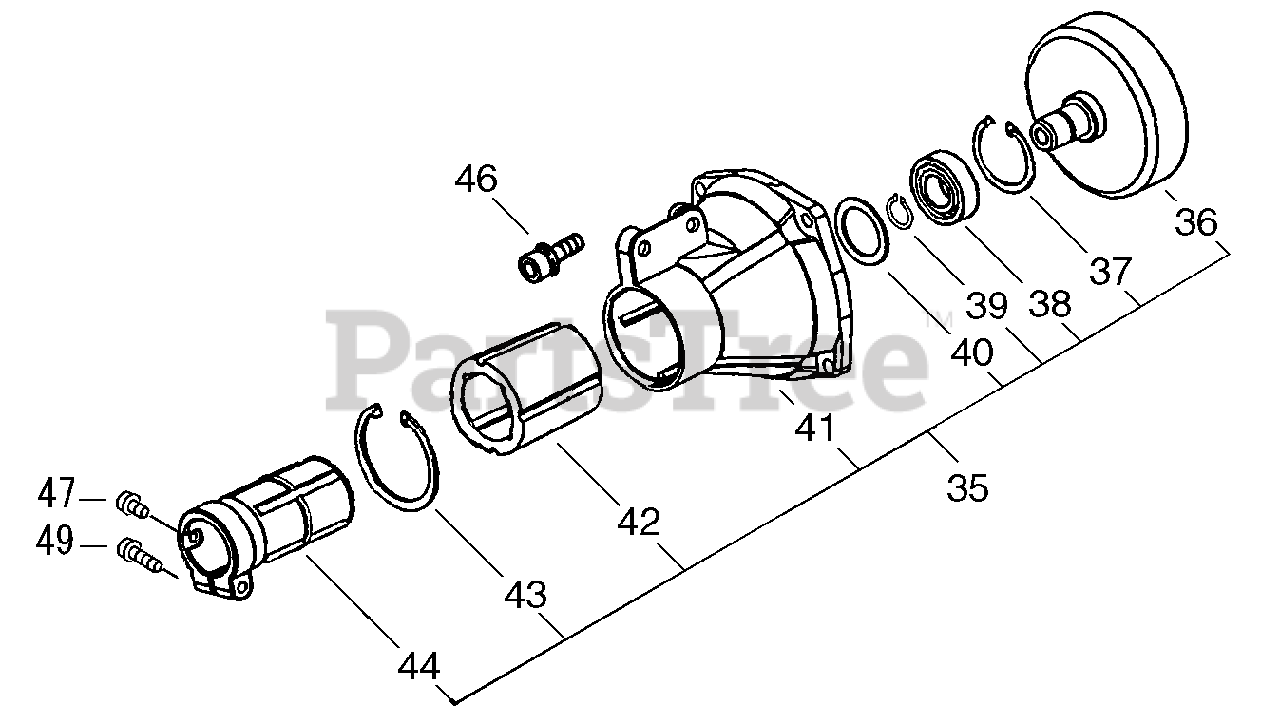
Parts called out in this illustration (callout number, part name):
35	FAN CASE ASSY
36	DRUM, CLUTCH
37	RING, RETAINING
38	BEARING, BALL - 6002
39	RING, RETAINING
41	CASE, CLUTCH
42	CUSHION
43	RING, RETAINING
44	JOINT
47	SCREW - 5X12
49	SCREW - 5X25
